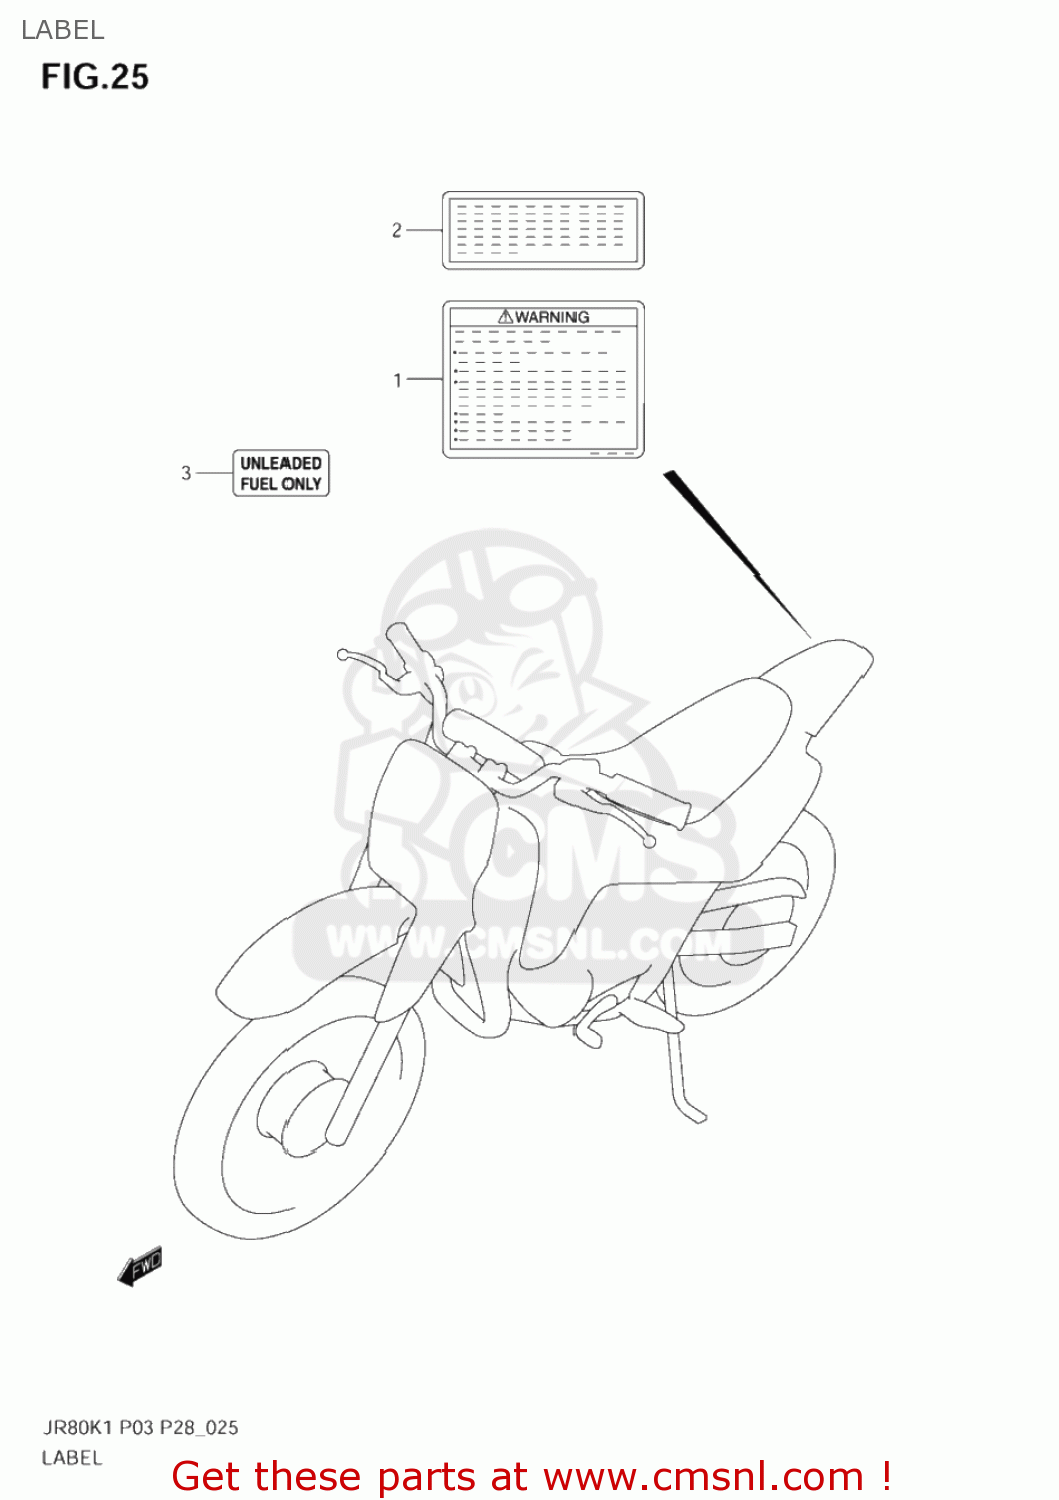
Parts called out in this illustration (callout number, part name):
1	LABEL,WARNING
2	LABEL,MANUAL NOTICE
3	LABEL,UNLEADED FUEL
4	MANUAL,OWNER'S
